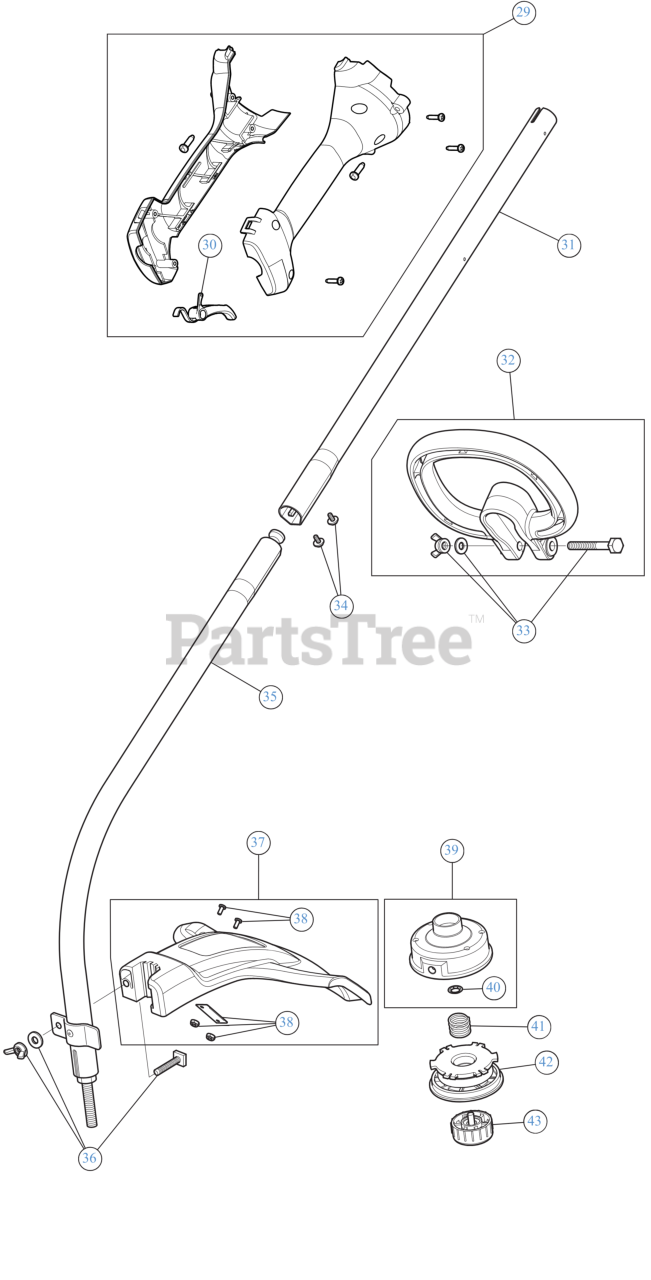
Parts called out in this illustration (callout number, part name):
29	THROTTLE GRIP ASSEMBLY
30	THROTTLE TRIGGER
31	UPPER BOOM ASSEMBLY
32	HANDLE
33	HANDLE HWD
34	SCREW 8-32X3/8
35	LOWER BOOM ASSEMBLY
36	BLADE GUARD MOUNTING HARDWARE
37	GUARD ASSEMBLY
38	BLADE ASSEMBLY CUTOFF
39	REEL:OTR W/RET
40	RETAINER .625 OD 2
41	SPRING-SPOOL
42	REEL-INNER SPOOL
43	BUMP HEAD KNOB ASSEMBLY
